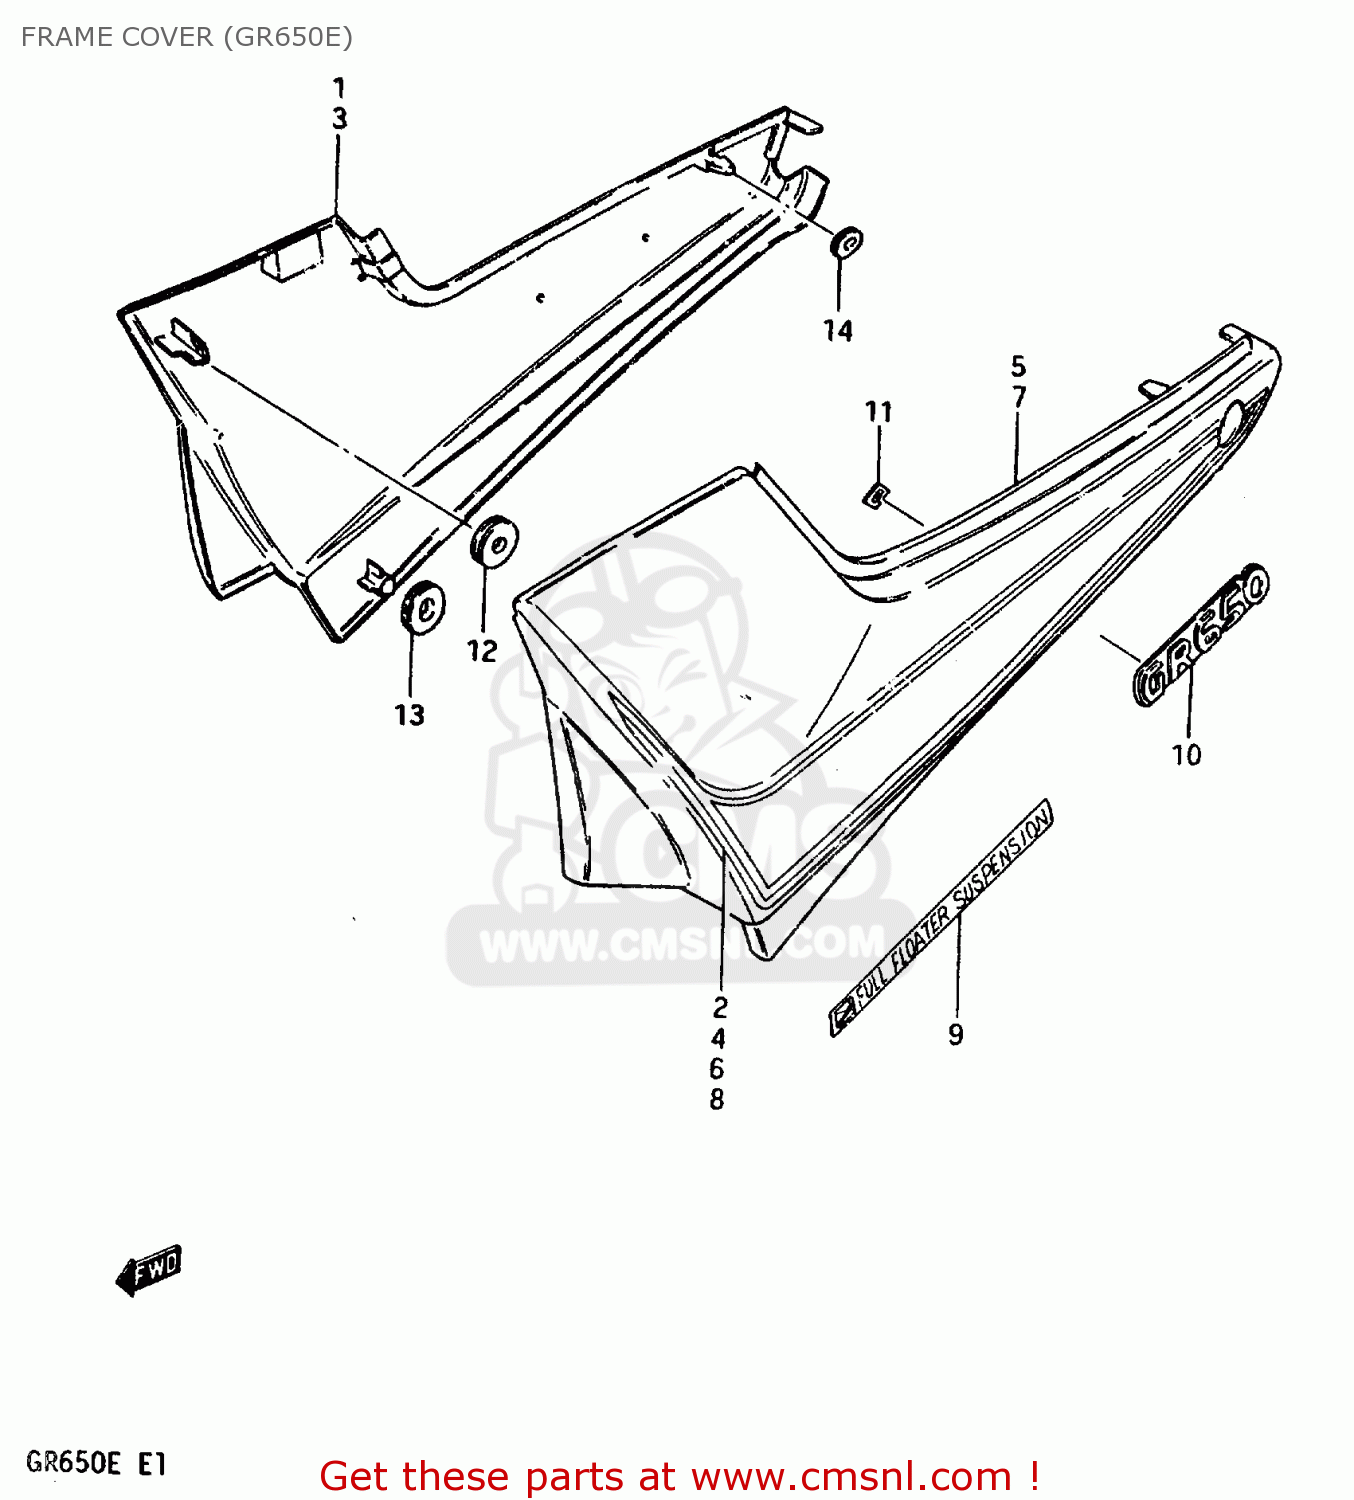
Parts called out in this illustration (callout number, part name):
1	COVER, FRAME RH
2	TAPE, RH
3	COVER, FRAME RH
4	TAPE, RH
5	COVER, FRAME LH
6	TAPE, LH
7	COVER, FRAME LH
8	TAPE, LH
9	EMBLEM
10	EMBLEM,FRAME COVER
11	NUT
12	CUSHION
13	CUSHION
14	CUSHION
